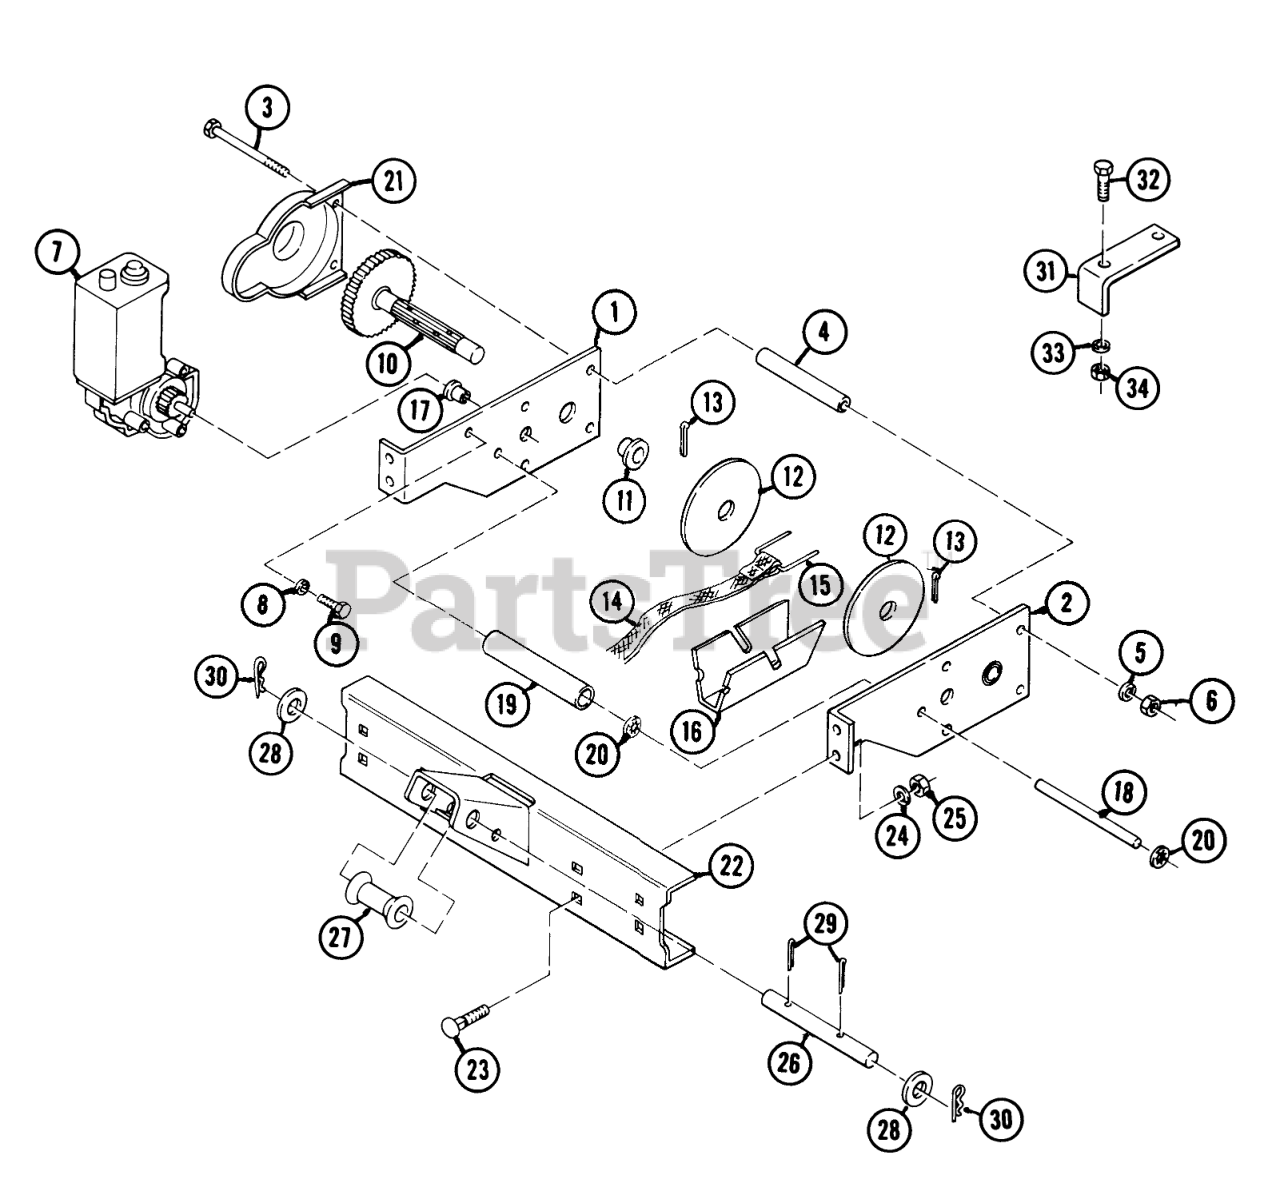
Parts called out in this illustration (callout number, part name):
7-01	Support, Right
7-02	Support, Left
7-03	Bolt, Hex 1/4-20 x 4 1/2
7-04	Spacer
7-05	Lockwasher 1/4
7-06	Nut, 1/4-20
7-07	Motor
7-08	Spacer
7-09	Hex Bolt 1/4-20 x 7/8
7-10	Gear Assembly
7-11	Bearing, Flgd.
7-12	Guide Washer
7-13	Cotter Pin
7-14	Lift Strap
7-16	Guard, Lift Strap
7-17	Flanged Bearing
7-18	Shaft
7-19	Sleeve
7-20	Push Nut
7-21	Gear Cover
7-22	Lift Yoke & Bumper
7-23	Carriage Bolt, 5/16-18 x 1
7-24	Lockwasher-5/16
7-25	Cotter Pin
7-26	Shaft
7-27	Spool
7-28	Washer, Plain 1/2
7-29	Cotter Pin
7-30	Hairpin Cotter
7-31	Extension Bar (Draw Bar Hitch)
7-32	Bolt, Hex 1/2-13 x 1 1/4
7-33	Lockwasher, 1/2
7-34	Nut, Hex 1/2-13
